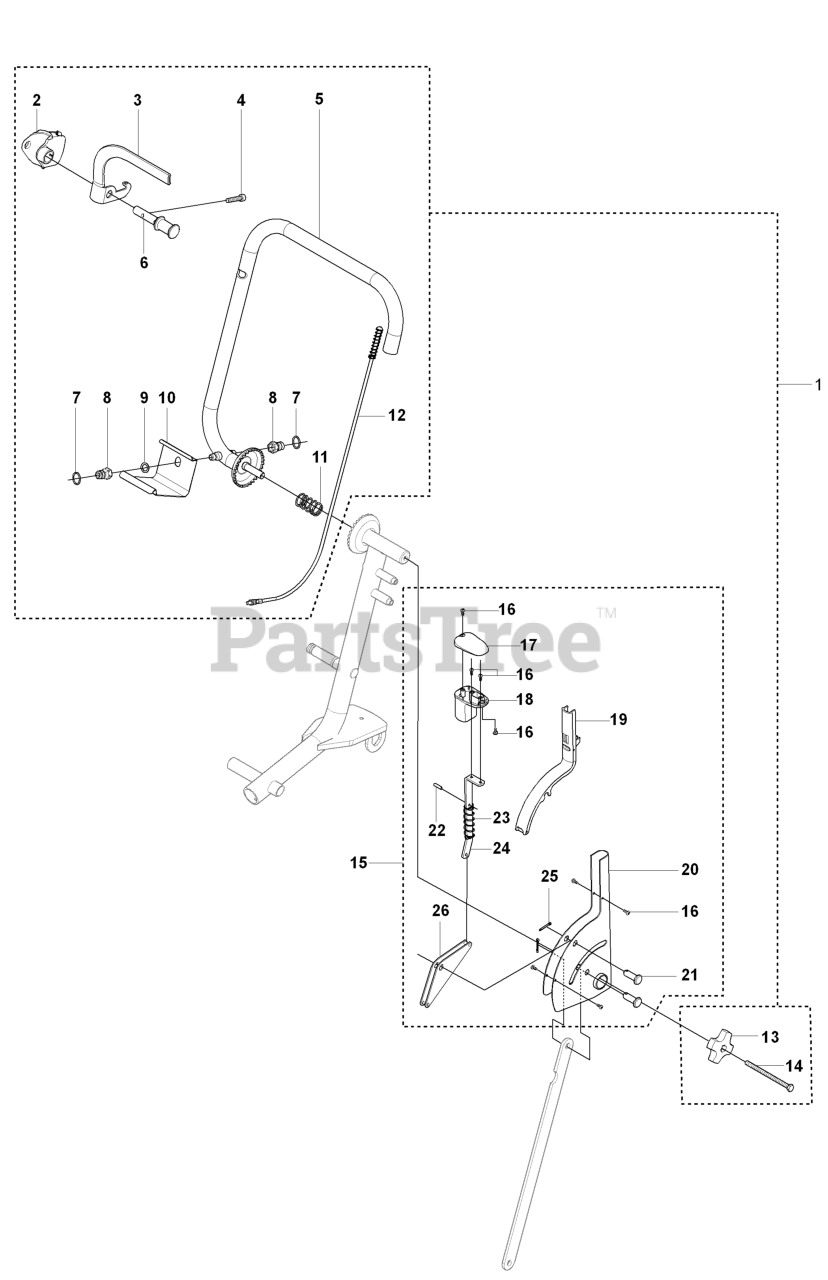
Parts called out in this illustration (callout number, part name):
1	HANDLEBAR ASSY
3	THROTTLE HANDLE ASSY
5	HANDLE
11	SPRING THROTTLE CONTROL
13	KNOB
15	LEVER
16	SCREW CROSS-SLOTTED
21	CLEVIS PIN 12X35X3.2 ISO 2341
22	PIN SPRING
25	LOCKING PIN. 3.2X22 ISO 1234
